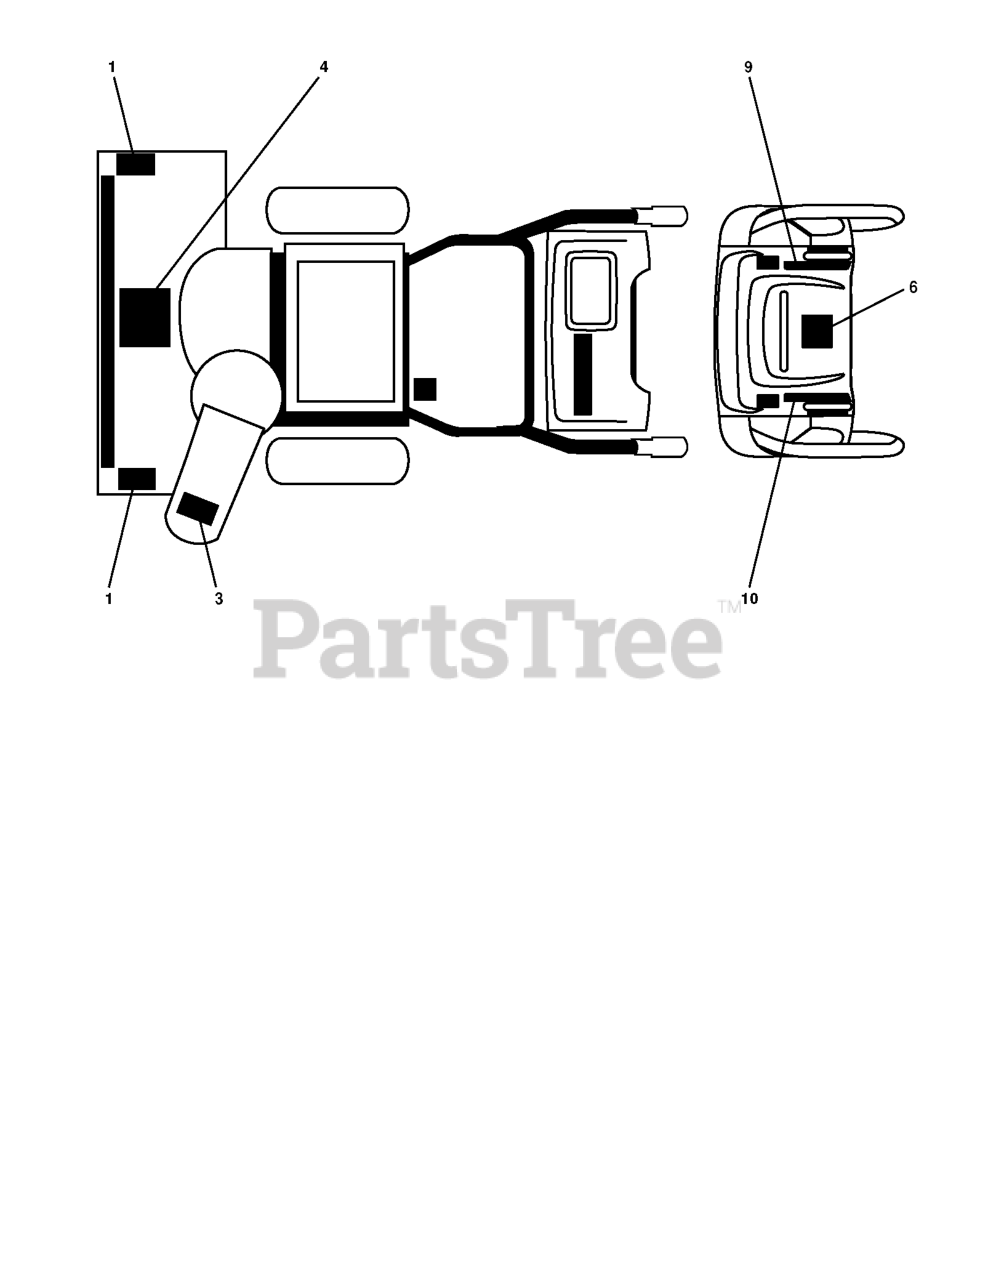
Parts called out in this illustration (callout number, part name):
1	DECAL.SNOWTHR.AUGER
3	DECAL.SNOWTHR.CHUTE.SAFETY
4	DECAL.SNOWTR.READ.OWN.MAN.E/F
6	DECAL, INSTRUCTION
9	DECAL SPEED CONTROL
10	DECAL, REMOTE DEFLECTOR
